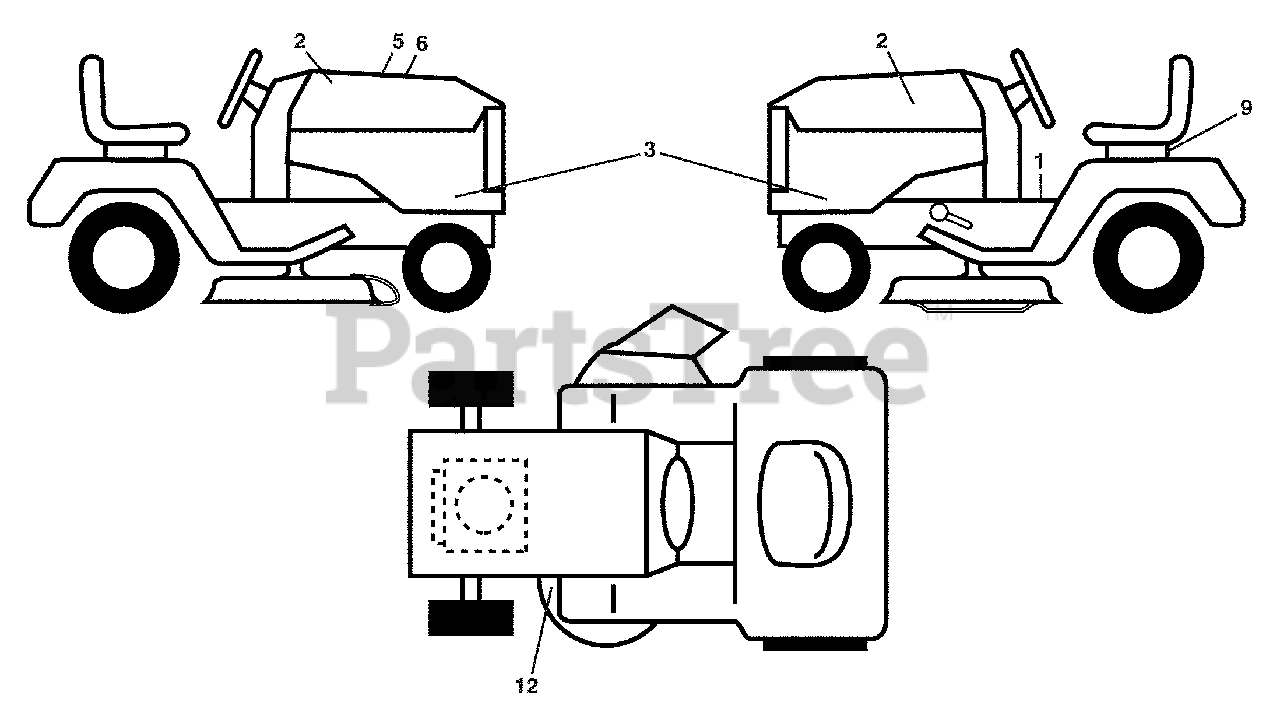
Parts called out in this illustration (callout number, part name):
1	Decal, Fender Warning
2	Decal, Hood
3	Decal, Hood Panel SD
5	Decal, Customer Respons.
6	Decal, Replacement
9	Decal, Battery Dnge/Poi
12	Decal, Mower V-Belt Schematic
